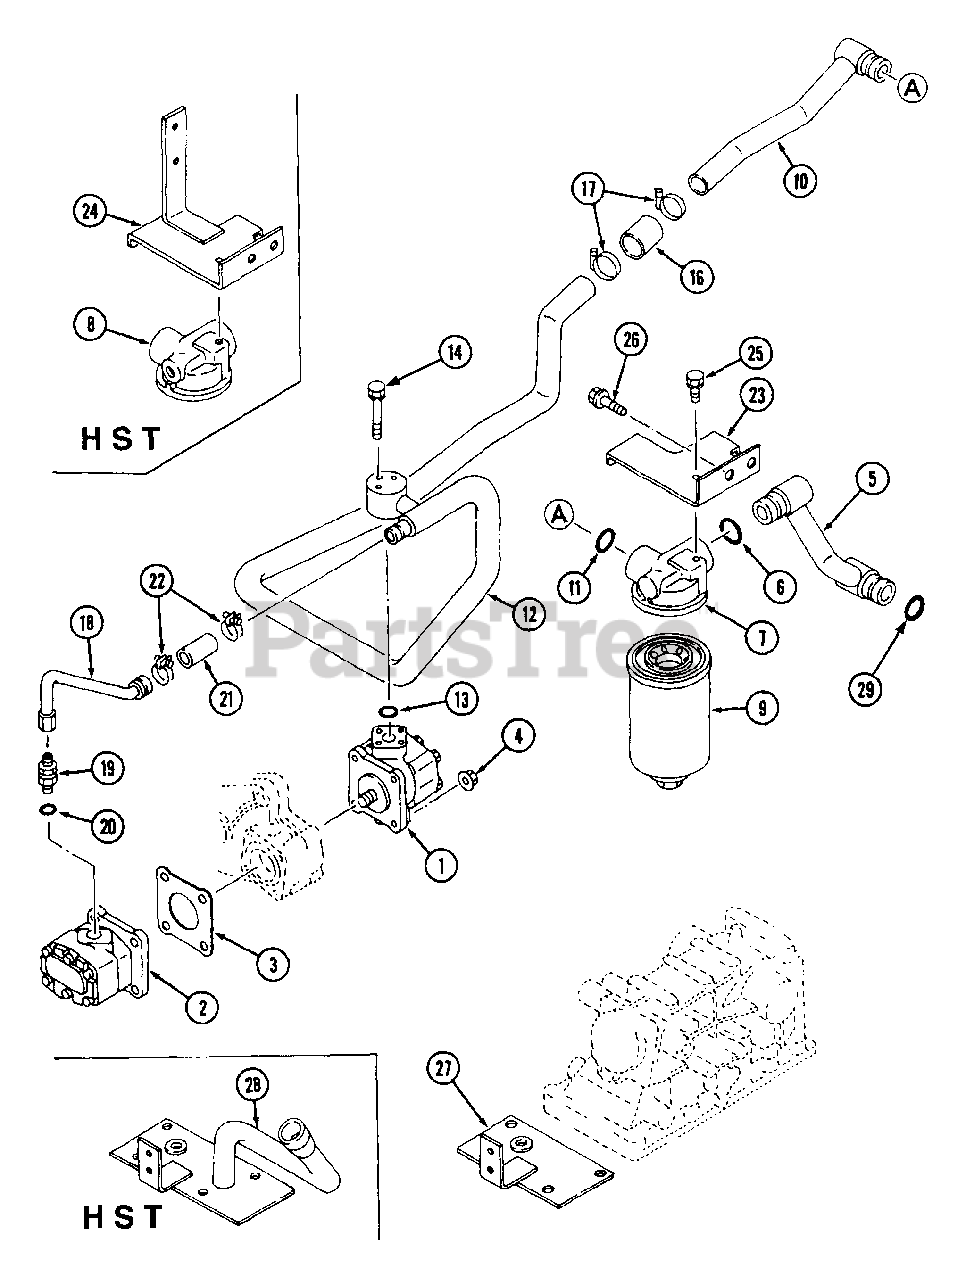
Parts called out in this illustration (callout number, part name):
1	Pump (Mod. No. 11-3844HL)
5	Pipe, A Suction
8	Base, Filter
10	Pipe, B Suction
12	Pipe, C Suction
18	Pipe, E Ass'y.
24	Bracket
28	Cover
29	O-Ring
